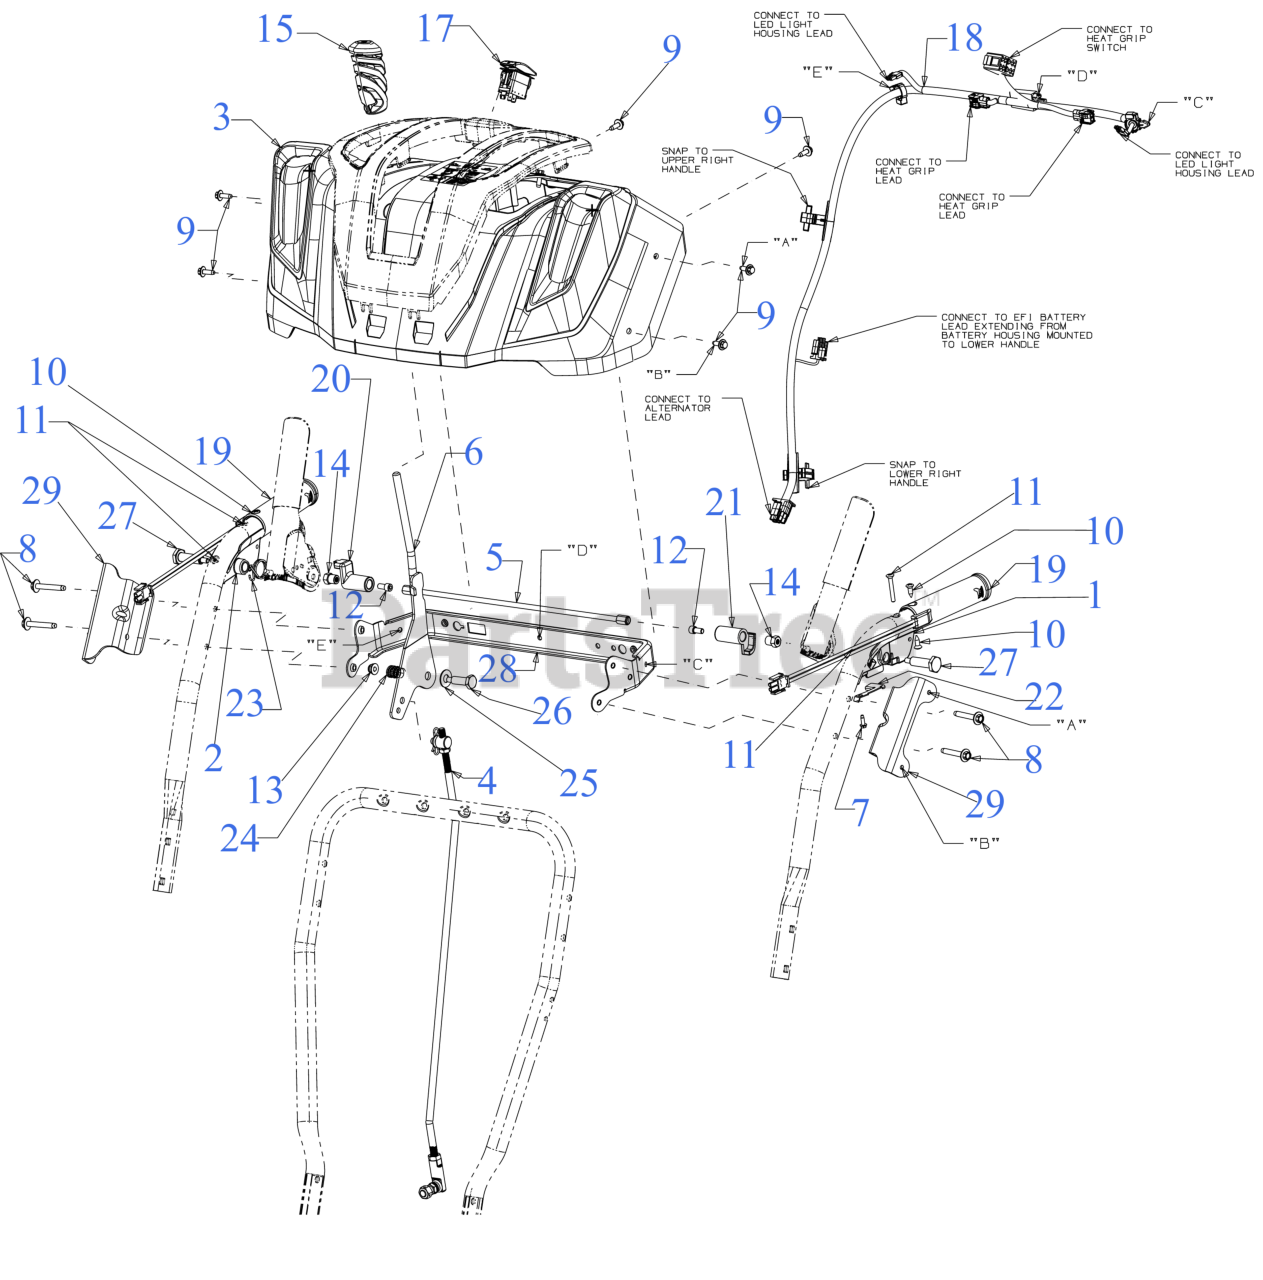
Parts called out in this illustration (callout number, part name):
1	CLUTCH LOCK HANDLE ASSEMBLY (LH)
2	CLUTCH LOCK HANDLE ASSEMBLY (RH)
3	HANDLE PANEL ASSEMBLY
4	SHIFT ROD ASSEMBLY
7	SCREW #8-16 x .50
8	SCREW 1/4-20 x 1.625
9	SCREW M6-1 x .625
10	SCREW-AB #12-24 x .625
11	SCREW #10-24 x 1.375
12	SCREW 1/4-20 x .50
13	FLANGE LOCK NUT
14	HEX NUT W/PATCH
15	PTO HANDLE GRIP .355 ID
17	HEATED GRIP SWITCH
18	HEADLIGHT HARNESS
19	HEATED GRIP
21	CLUTCH LOCK CAM
22	CLUTCH SPRING
23	TORSION SPRING
24	COMPRESSION SPRING
25	FLAT WASHER .38X.88
25	FLAT WASHER .401X.88
26	SHOULDER SCREW
27	SHOULDER SCREW .437 x 1.345 1/4-20
